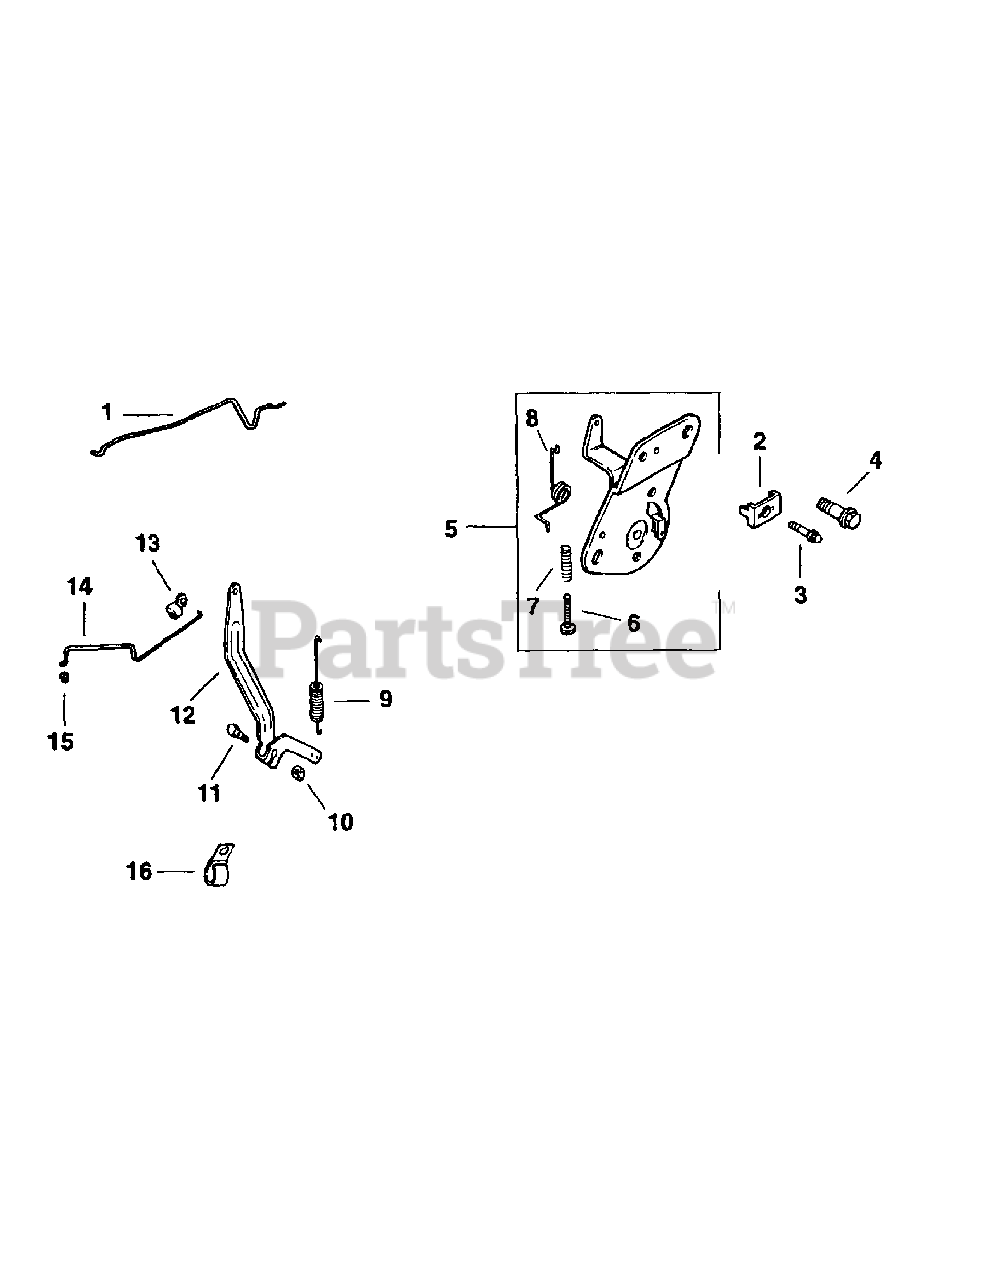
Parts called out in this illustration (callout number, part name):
1	Linkage, Choke
2	Clamp, Cable
3	Screw, Hex Flange
4	Screw, Hex Flange
5	Speed Control Assembly
6	Screw, Pan hd.
7	Spring, Choke
8	Spring, Choke Return
9	Spring, Governor
10	Nut, Hex Flange
11	Screw, Hex Cap
12	Lever, Governor
13	Bushing, Linkage Black
14	Linkage, Throttle
15	Bushing, Linkage Natural
